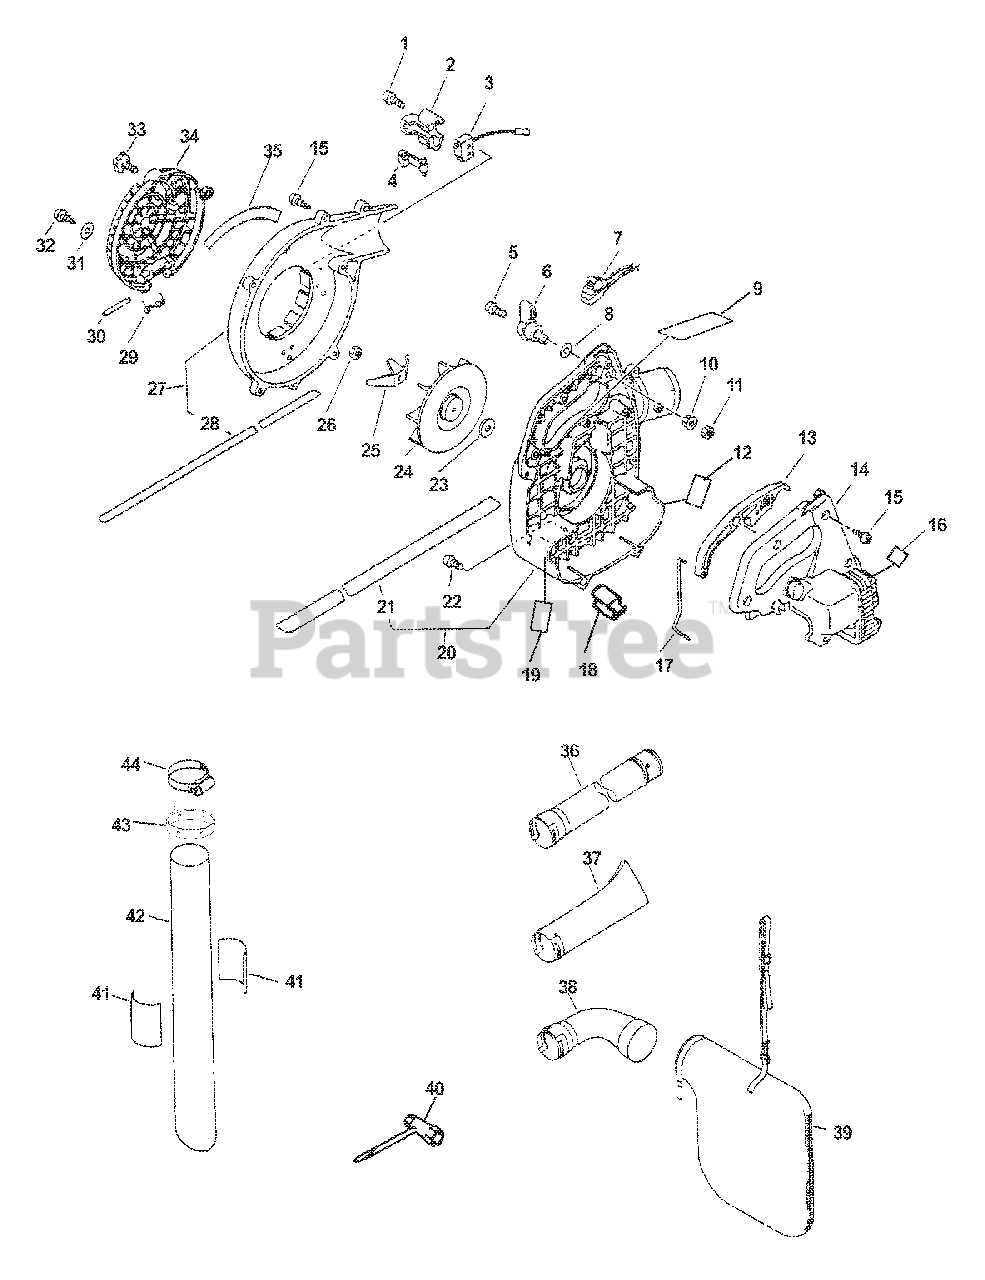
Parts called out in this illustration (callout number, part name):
1	SCREW 4×22
2	BRACKET, SWITCH
3	SWITCH, INTERLOCK
4	LEVER, SHUT OFF ACTUATOR
5	SCREW 5×25
6	CONTROL, THROTTLE
7	IGNITION SWITCH ASSY
8	WASHER 5.5×12×0.8
9	LABEL, CAUTION
10	NUT, FLANGE M5
12	LABEL - CAUTION -- SPANISH
13	CONTROL, THROTTLE
14	COVER, ENGINE
15	SCREW, TAPPING 5×20
16	LABEL, CAUTION - HOT
17	ROD, THROTTLE
19	LABEL - CAUTION
20	FAN COVER ASSY - RIGHT
21	CUSHION
22	SCREW 4×22
25	SHREDDER
27	FAN COVER ASSY - LEFT
28	CUSHION
29	SPRING, COIL
30	PIN, INTAKE COVER
31	WASHER 5.5×12×0.8
32	SCREW 5×14
33	THUMBSCREW
34	COVER, INTAKE
35	LABEL - MODEL
36	TUBE, BLOWER - STRAIGHT
37	TUBE, BLOWER - NOZZLE
39	BAG, DUST
40	T-WRENCH 13×19×180
41	LABEL - SHRED 'N' VAC
42	TUBE, VACUUM
